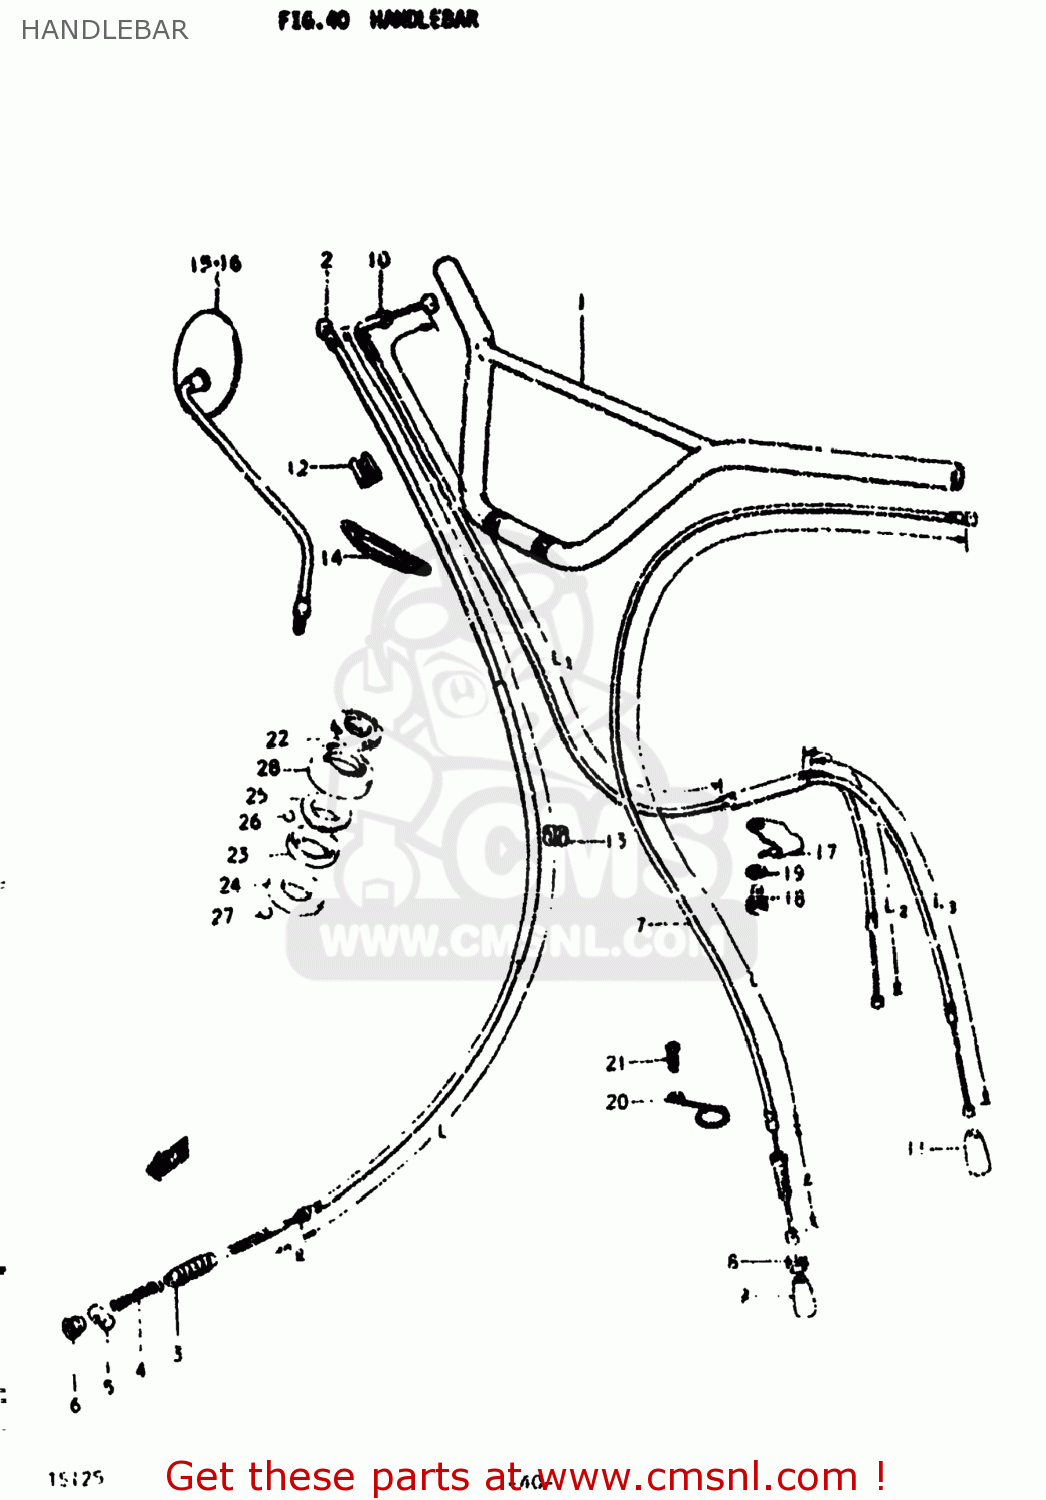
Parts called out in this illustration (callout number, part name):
1	HANDLEBAR
2	CABLE ASSEMBLY,FRONT BRAKE
3	SEAL,DUST(7X16X75)
4	SPRING
5	PIN,10X19
6	NUT
7	CABLE ASSY,CLUTCH
8	NUT
9	SEAL,DUST(7X18X30)
10	CABLE ASSEMBLY,THROTTLE
11	SEAL,DUST(7X18X30)
12	CLIP
13	CLIP
14	GUIDE,CABLE
15	MIRROR ASSEMBLY,RIGHT
16	MIRROR ASSEMBLY,LEFT
17	CLAMP
18	BOLT
19	LOCK WASHER
20	CLIP
21	SCREW
22	NUT,STEERING STEM(25X44X10)
23	RACE,STEERING INNER UPR
24	LACE,STEERING INNER LWR
25	RACE,STEERING OUTER UPR
26	BALL
27	BALL
28	DUST SEAL,STEERING UPR
